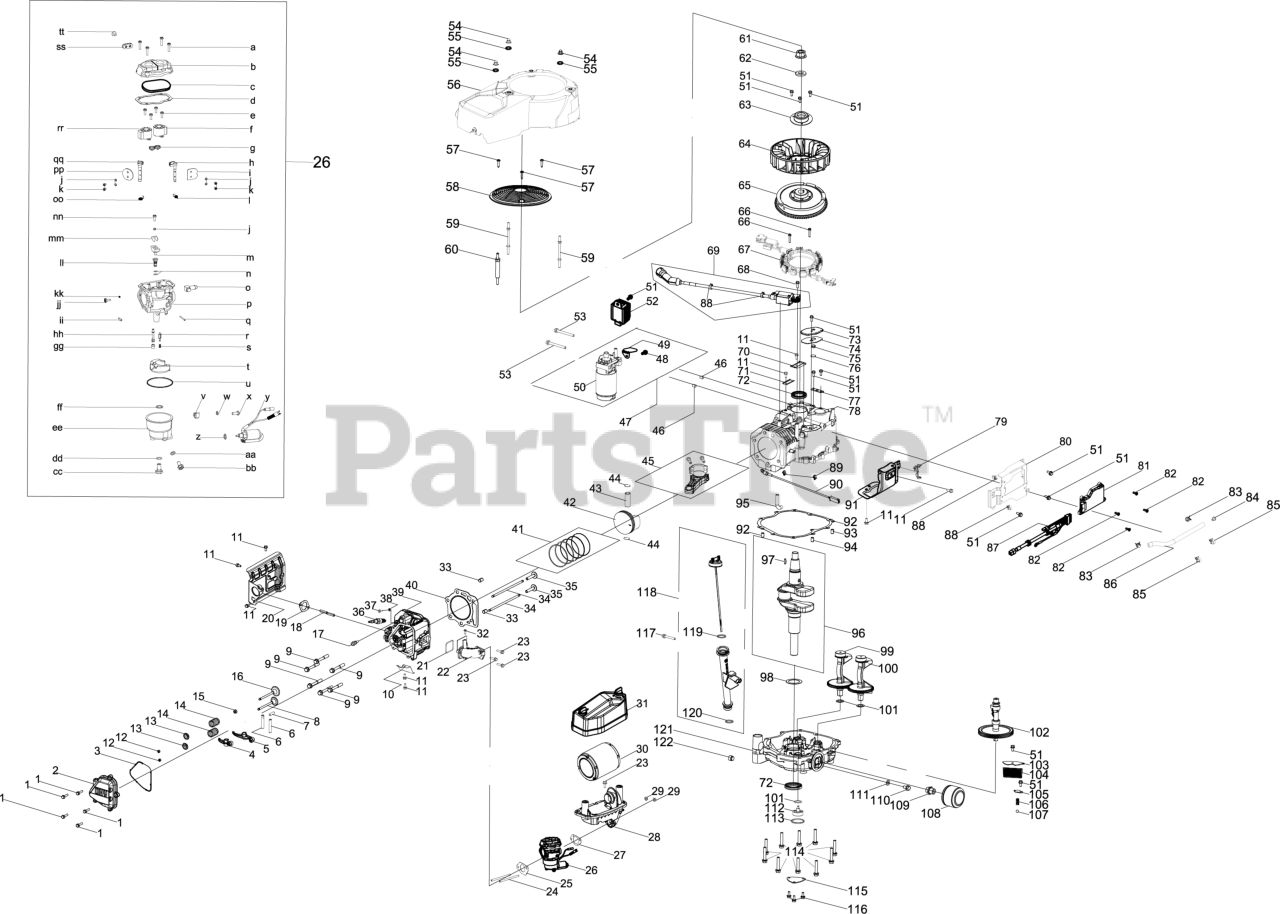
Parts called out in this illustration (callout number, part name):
1	BOLT M6-1 x 25 GR8.8
2	VALVE COVER
3	VALVE COVER GASKET
4	ROCKER ARM (EXHAUST)
5	ROCKER ARM (INTAKE)
6	ROCKER ARM SHAFT
7	CAMSHAFT PIN
8	EXHAUST VALVE
9	BOLT M10-1.25 x 70
10	HEAT SHEILD
11	BOLT M6-1 x 12 GR8.8
13	VALVE SPRING SEAT
14	VALVE SPRING
15	INTAKE VALVE SEAL
16	INTAKE VALVE
19	EXHAUST GASKET
20	BAFFLE BRACKET
21	INTAKE PIPE RING
22	INTAKE MANIFOLD
23	BOLT M6 x 22
24	STUD M6-1.00 x 92
25	INTAKE GASKET
26	CARBURETOR
27	AIR FLTER GASKET
28	AIR FILTER BASE
30	AIR FILTER W/PREFILTER
31	AIR FILTER COVER
32	BOLT 5.5 x 25
34	SINGLE PUSH ROD
36	SPARK PLUG (F6RTC/RN11YC/BPR6ES)
37	BOLT M5-.8 x 10
38	FLAT WASHER: 5.3 x 10 x 1
39	CYLINDER HEAD
40	CYLINDER HEAD GASKET
41	PISTON RING SET
43	PISTON PIN
44	PISTON PIN SNAP RING
45	CONNECTING ROD
47	ELECTRIC STARTER
48	BOLT M6 x 16
49	STARTER SHIELD BRACKET
50	Electric Starter
51	BOLT M6-1 x 14 GR8.8
53	BOLT M8-1.25 x 80
54	ACORN NUT M6-1
56	ENGINE SHROUD
57	BOLT 5.5 x 25
58	DEBRIS SHIELD
60	STUD M6 X 113
61	NUT M20 x 1.5
62	WASHER 20.5 x 5 x 40
63	COOLING FAN PLATE
64	COOLING FAN
66	BOLT M5 x 28
67	ALTERNATOR
68	BOLT-M6-1 x 28 GR8.8
69	IGNITION MODULE
70	WIRE PLATE
71	BREATHER SCREEN
72	OIL SEAL 38 x 58 x 8
73	BREATHER COVER
74	BREATHER COVER GASKET
75	BREATHER VALVE SPRING
76	BREATHER VALVE
80	ECM MOUNT BRACKET
81	ENGINE CONTROL MODULE
82	SCREW M4x12
83	CARBURETOR HOSE CLAMP
85	FUEL LINE SUPPORT CLAMP
86	FUEL HOSE LOW PERMEATION
88	WIRE SUPPORT CLAMP
90	TEMPERATURE SENSOR
91	SHROUD - RIGHT
92	CRANKCASE COVER GASKET
93	DOWEL PIN 9 X 14
94	DOWEL PIN 7 X 14
95	VENTING HOSE
96	CRANKSHAFT ASSEMBLY
96	DRIVE TIMING GEAR
96	BALANCE SHAFT GEAR
97	WOODRUFF KEY
98	WASHER 38.3 x 54 x 1
99	BALANCE SHAFT (LH)
100	BALANCE SHAFT (RH)
101	WASHER 17.2 x 26 x 1
103	FILTER COVER
104	FILTER SCREEN
105	PRESSURE RELEASE COVER
106	PRESSURE RELEASE SPRING
107	OIL PUMP STEEL BALL
108	ENGINE OIL FILTER
109	SCREW JOINT OIL FILTER ADAPTER
110	BOLT M8 x 15
111	OIL DRAIN PLUG WASHER
112	OIL PUMP ASSEMBLY
114	BOLT M8 x 45
115	OIL SEPARATOR
116	Bolt, M6X12
117	BOLT M6-1 x 45 CL5.8
118	DIPSTICK ASSEMBLY
121	CRANKCASE COVER
122	ENGINE PLUG 3/8 NPT
